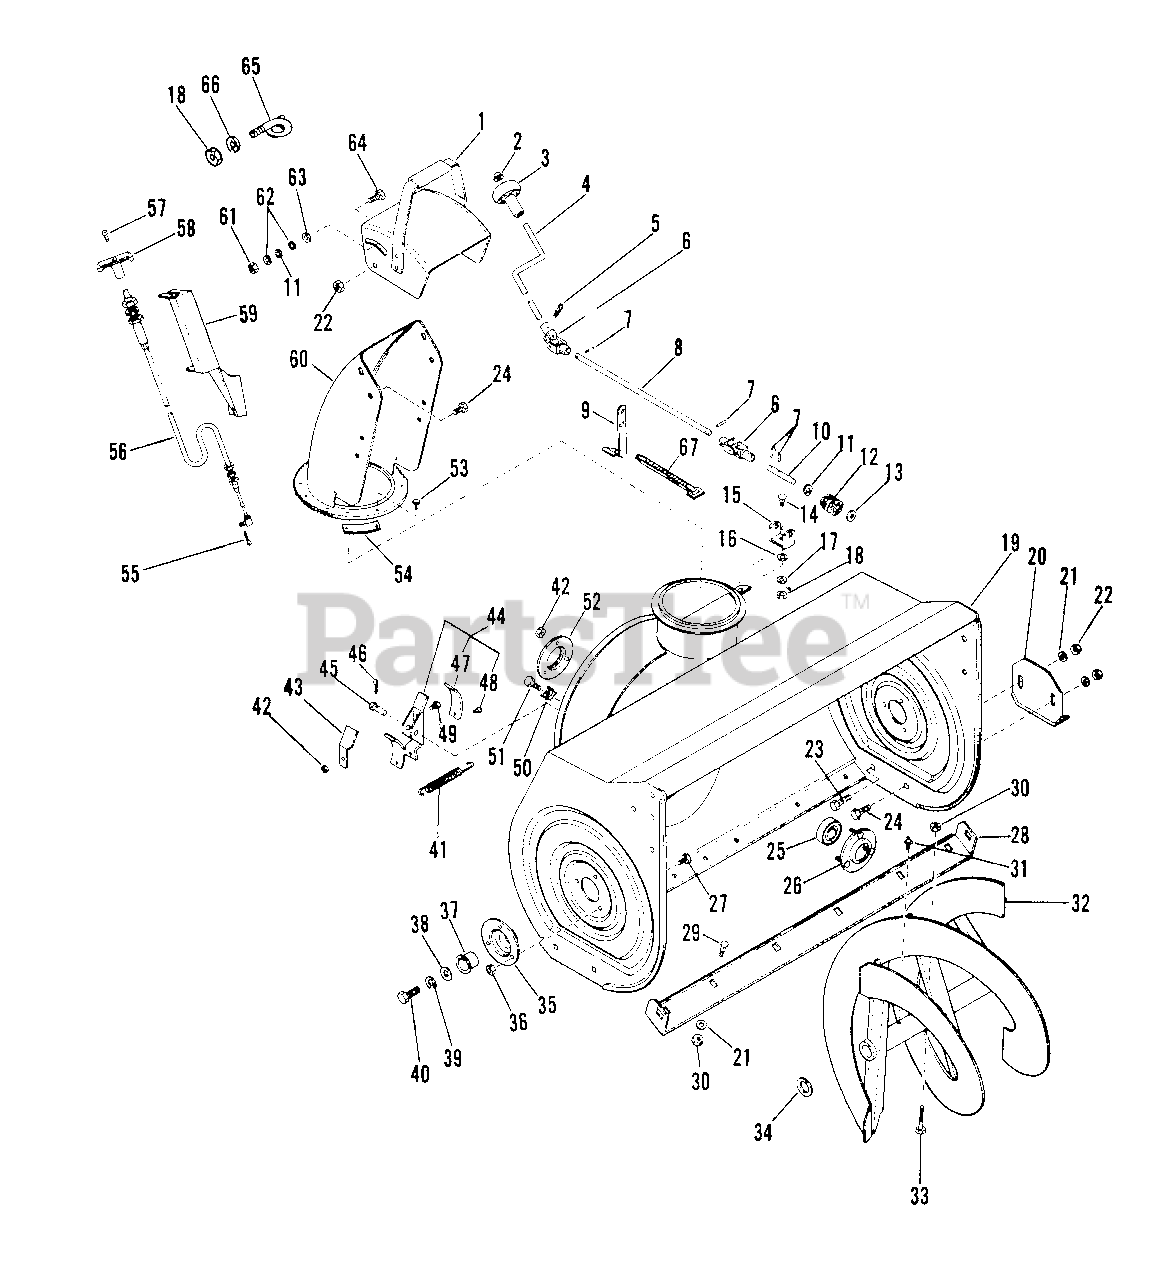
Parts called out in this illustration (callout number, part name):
1	CHUTE DEFLECTOR W/DECAL
1	DEFLECTOR W/DECAL
2	CAP, 3/8 ROD YWZC
4	CHUTE CONTROL CRANK
5	PIN-COTR .12X1.0 PL
5	PIN-HAIR INT .08X.38X1.42 YWZC
6	UNIVERSAL JOINT ASSEMBLY
7	PIN-ROLL .125X.75
8	ROD
9	CHUTE CRANK BRACKET
10	WORM SHAFT
11	WAVE WASHER .406X.750X.063FH
11	WAVE WASHER .390X.655X.110
12	WORM GEAR L.H.
13	WSHR-PLASTIC .390X.875X.062
14	BLT-RDHDSQNK .31-18X.75 SHT PL
15	WORM CLEVIS
16	WSHR-LK-EXT .375X.035 PL
17	WSHR-LK .313X.062
18	NUT-HEX .312-18
19	BLOWER HOUSING W/DECALS
19	BLOWER HOUSING W/DECALS 24
19	BLOWER HOUSING W/DECALS 32
19	BLOWER HOUSING W/DECALS 36
19	BLOWER HOUSING W/DECALS 28
20	RUNNER
20	RUNNER-SKID SHOE
21	WSHR-FL-STL .38X.875X.083 PL
22	NUT-LK-CTR .375-16 GR A PL
23	BLT-RDHDSQSHNK .38-16X1.00 PL
24	BLT-RDHDSQNK .38-16X.75 SHT PL
25	BRG-BALL 1.0X2.0X.56
25	BRG-BALL .750X1.750X.50
25	BRG-BALL1.0X2.0X.56
26	BEARING FLANGE
27	BLT-SERNK SL .25-20X.50 PL
28	SCRAPER BLADE 24"
28	SCRAPER BLADE 32"
28	SCRAPER BLADE 28"
28	SCRAPER BLADE 36"
29	BLT-RDHDSQNK .312-18X.62SHTPL
30	NUT-LK .312-18 GR A PL
31	SPIN DRIVE ZERK FITTING
32	RAKE, RIGHT-32"(1ID X 15.75OD)
32	RAKE, LEFT-32"(1"ID X 15.75OD)
32	RAKE, RIGHT-24"(1ID X 14.75OD)
32	RAKE, LEFT-24"(1"ID X 14.75OD)
32	RAKE, RIGHT-28"(1ID X 15.75OD)
32	RAKE, LEFT-28"(1"ID X 15.75OD)
32	RAKE, RIGHT-36"(1ID X 15.75OD)
32	RAKE, LEFT-36"(1"ID X 15.75OD)
33	SHEAR BOLT SERVICE ASSEMBLY
34	WSHR-FL-STL 1.010X1.505X.062PL
35	BEARING SUPPORT
36	NUT-LK-FLG .250-20 PL
37	BSHG-FLG 1.000X1.12X.62X1.50BR
38	WSHR-FL-STL .511X1.441X.125 PL
39	WSHR-LK .500X.151 HVY PL
40	BLT-HEX .50-13X1.00 PL GR2
41	SG-TENS .062X.56X8.0 WLD 11
42	NUT-LK-CTR .250-20 PL
43	ARM EXTENSION
44	BRAKE ARM ASSEMBLY
45	PIN-CLEV .371X1.16 YWZC
46	PIN-COTR .062X.75 PL
47	BRAKE LINING
48	RVT-TBLR .187X.437 RH ST PL
49	BLT-HEX .25-20X.63 PL GR2
50	NUT-RETNR .38-16 TINRMAN
51	BLT-SCRHFWH .38-16X.75 PL
52	BEARING FLANGE
53	SCR-TAP 10-24X.484 HWH TR
54	CHUTE CLAMP
55	PIN-COTR .09X.75 PL
56	CONTROL CABLE
57	SCR-MCH 10-32X.50 SLPAN SS
58	TEE HANDLE
59	BRACKET - DEFLECTOR CONTROL
60	DISCHARGE CHUTE
60	DISCHARGE CHUTE - 36 IN
61	NUT-JAM .375-16 PL
61	NUT-LK-CTR .375-16 GR A PL
62	WSHR-FL-STL.406X.812X.065PL
62	WSHR-FL-STL .390X.875X.18 PL
63	WSHR-PLASTIC .390X.875X.062
64	BLT-HEX .38-16X.75 PL GR2
65	CABLE GUIDE
66	WSHR-LK .312X.097 PL HVY
67	CABLE TIE LG 8-7/8
